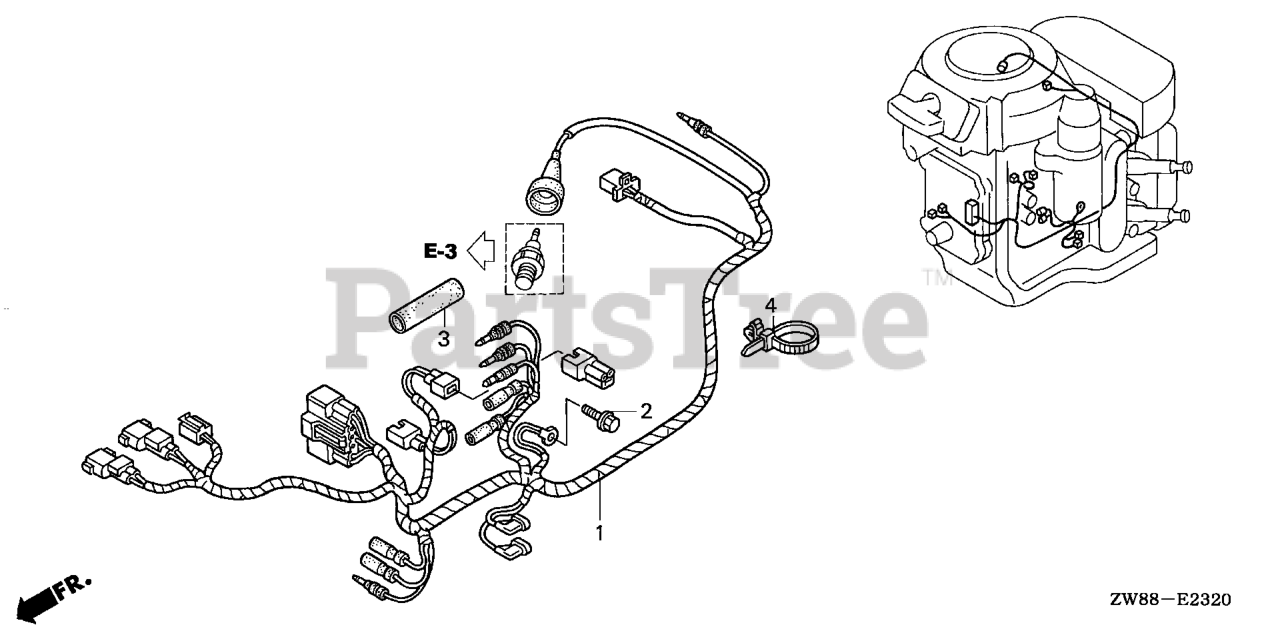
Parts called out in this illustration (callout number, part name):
1	WIRE HARNESS ASSY.
1	WIRE HARNESS ASSY. (R/C)
2	BOLT, FLANGE (6X12)
3	TUBE, RUBBER (11.5X14.5)
4	BAND, WIRE (95MM)
